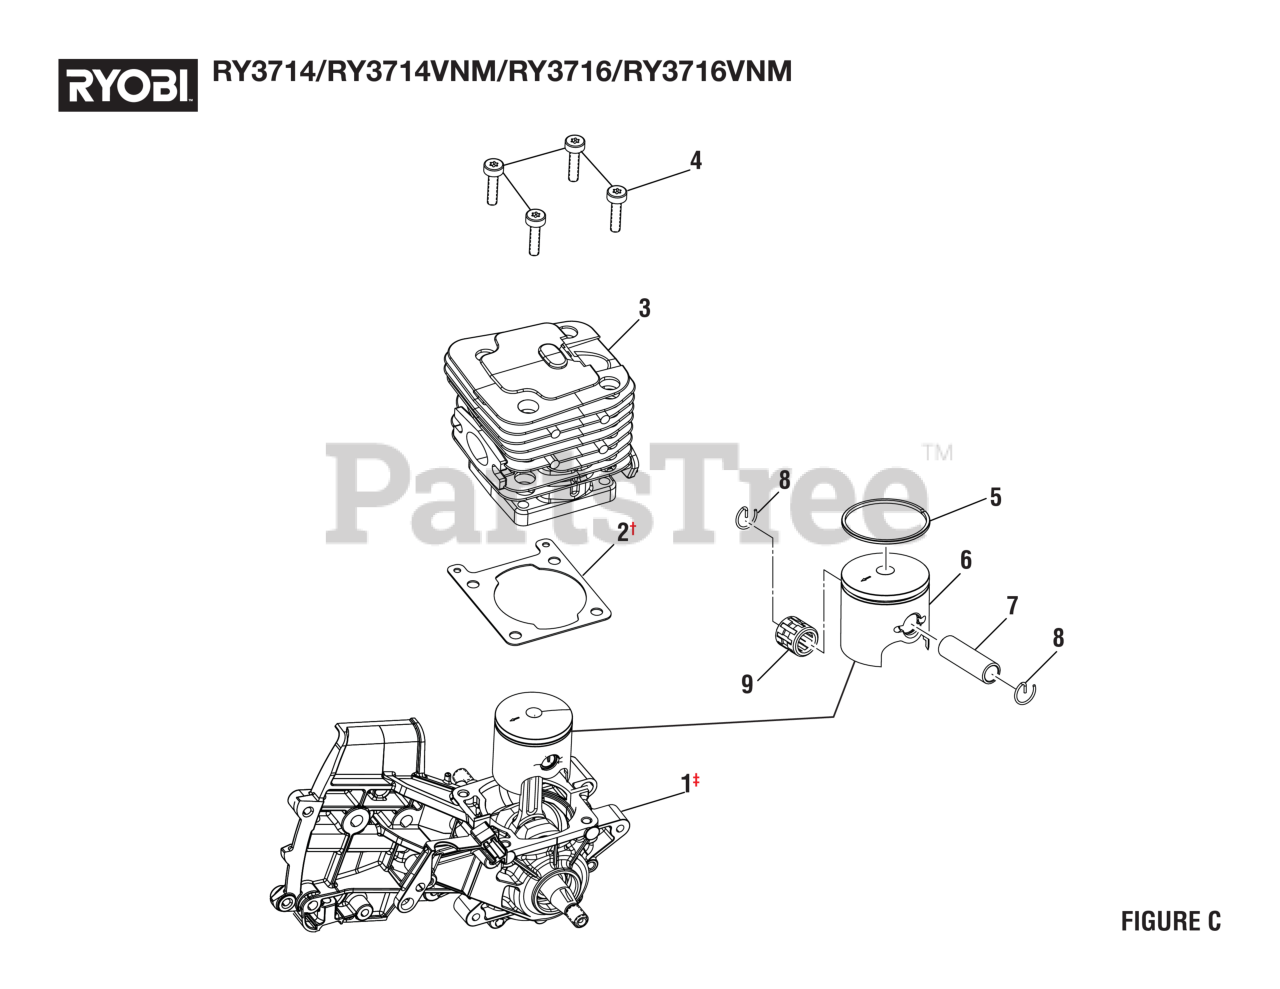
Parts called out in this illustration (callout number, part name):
1	Crankcase & Crankshaft Assembly
2	Crankcase Gasket
4	Cap Screw (M5 x 20 mm, T25 Torx Soc. Hd.)
5	Piston Ring
7	Piston Pin
8	Piston Pin Clip
9	Needle Bearing
